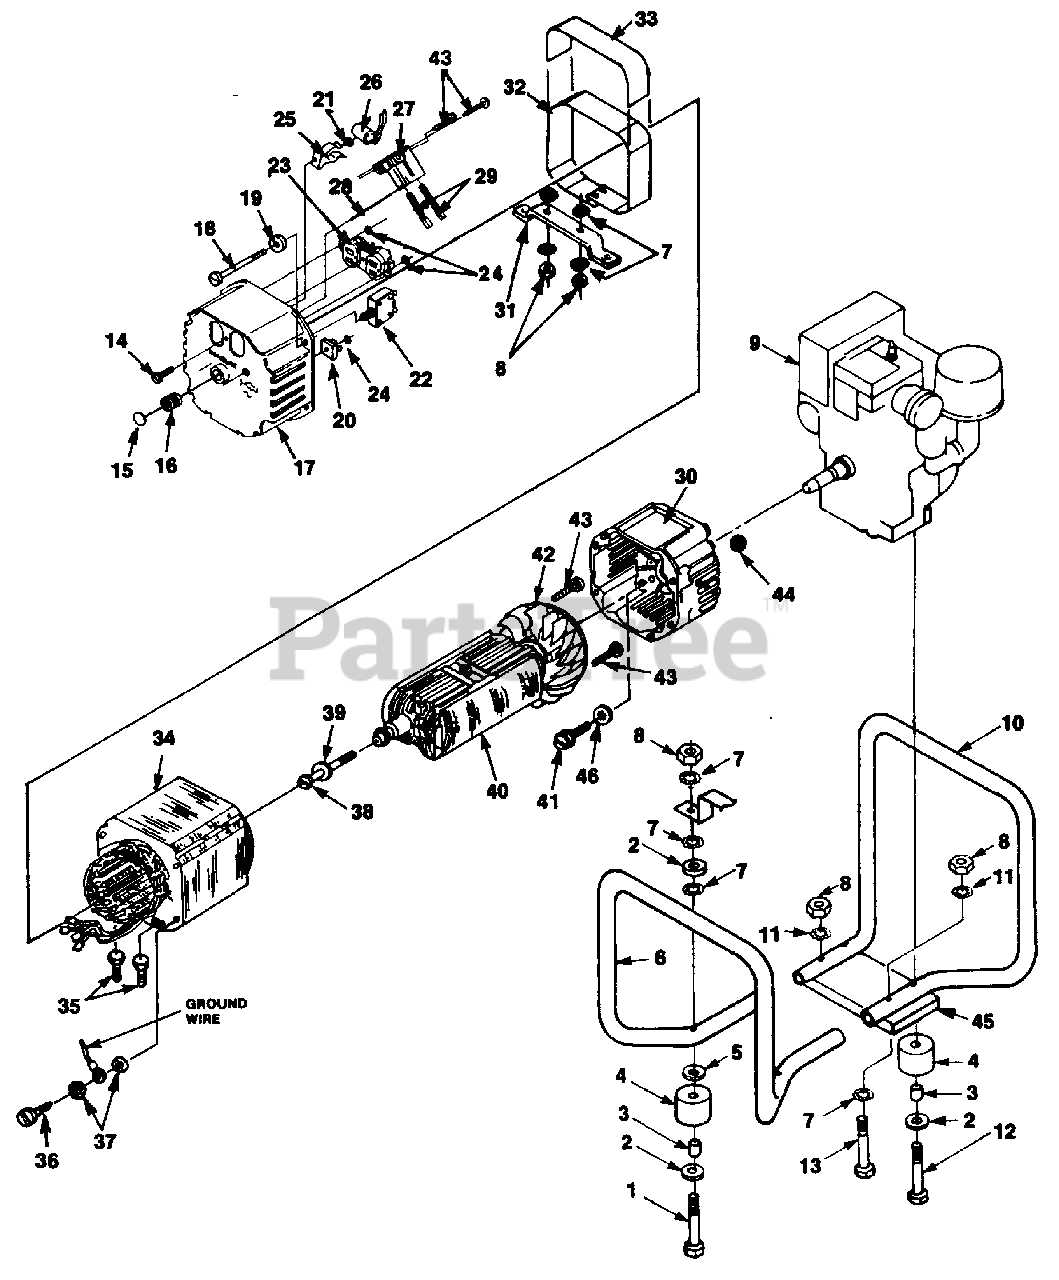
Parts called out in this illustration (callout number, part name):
2	WASHER- Flat (5/16")
3	SPACER- Foot
5	WASHER- Flat (5/16")
6	MEMBER- Frame (gen. end)
7	WASHER- Lock (ext./Int.)
8	NUT- Hex (5/16-18)
9	ENGINE
10	MEMBER- Frame (eng. end)
11	WASHER- Lock (Int.)
12	SCREW- (5/16 x 31/4")
14	SCREW- Mach. pan hd.
15	PLUG- Expansion
16	BEARING- Needle
17	BRUSH HEAD
18	BOLT- Stator
19	WASHER- Flat
20	RECTIFIER
21	WASHER- Shaft retention
22	BREAKER- Circuit (20 amp.)
23	RECEPTACLE- Duplex (Nema 5-20R)
24	WASHER- Shaft Retention
25	CLIP- Spring cap
26	CAPACITOR (w/Lead)
27	BRUSH HOLDER
29	BRUSH
30	BELL- End
31	BRACKET- Generator support
32	WRAPPER- Stator
33	DECAL- Warning
35	SCREW- 5/16-18 x 3/4"
37	WASHER- Lock (int./ext)
38	BOLT- Rotor
39	WASHER
41	SCREW
42	FAN- Generator
43	SCREW- Pan hd.
44	NUT- Hex
45	PLATE- Frame
46	WASHER- Lock
